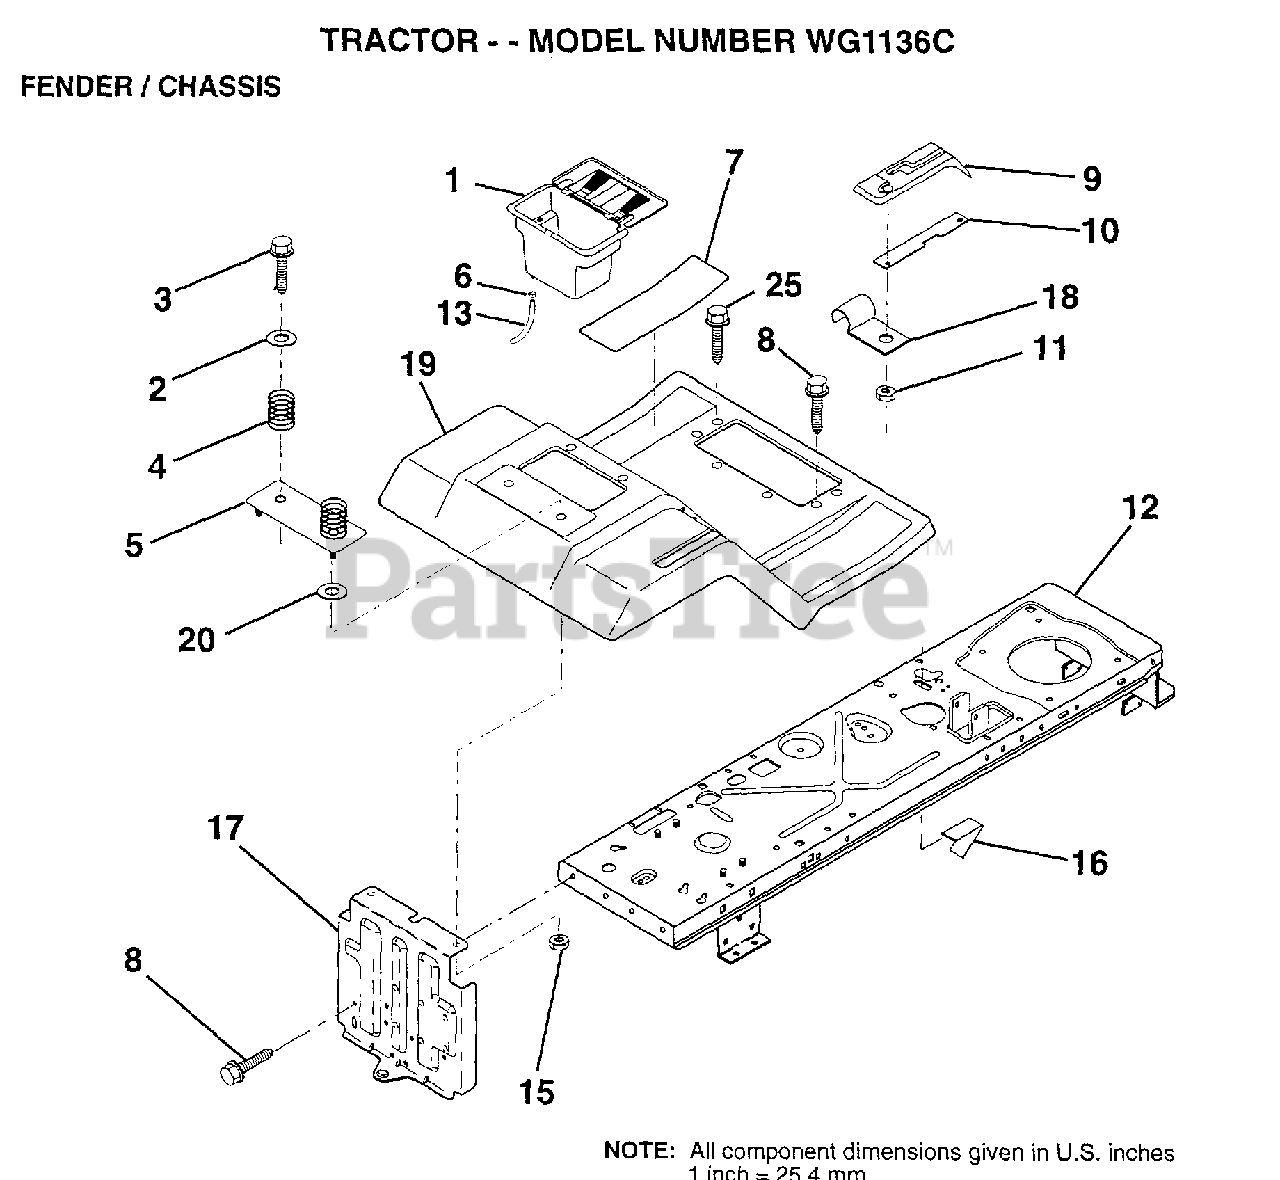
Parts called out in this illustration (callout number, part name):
2	WASHER
3	SCREW
4	SPRING COMPRESSIO
5	PLATE.FEND.LR.ASM
6	HOSE CLAMP T
7	PAD FOOTREST
8	SCREW
9	CONSOLE SHFT 5SP
10	PLATE LOCK SHIFT
11	NUT
12	CHASSIS.WELD.ASM.
13	TUBE T
15	NUT HXKEP 1/4X20
17	DRAWBAR ASM LR
18	"CLIP,INSULATOR"
19	FENDER/FOOTREST
25	SCREW
